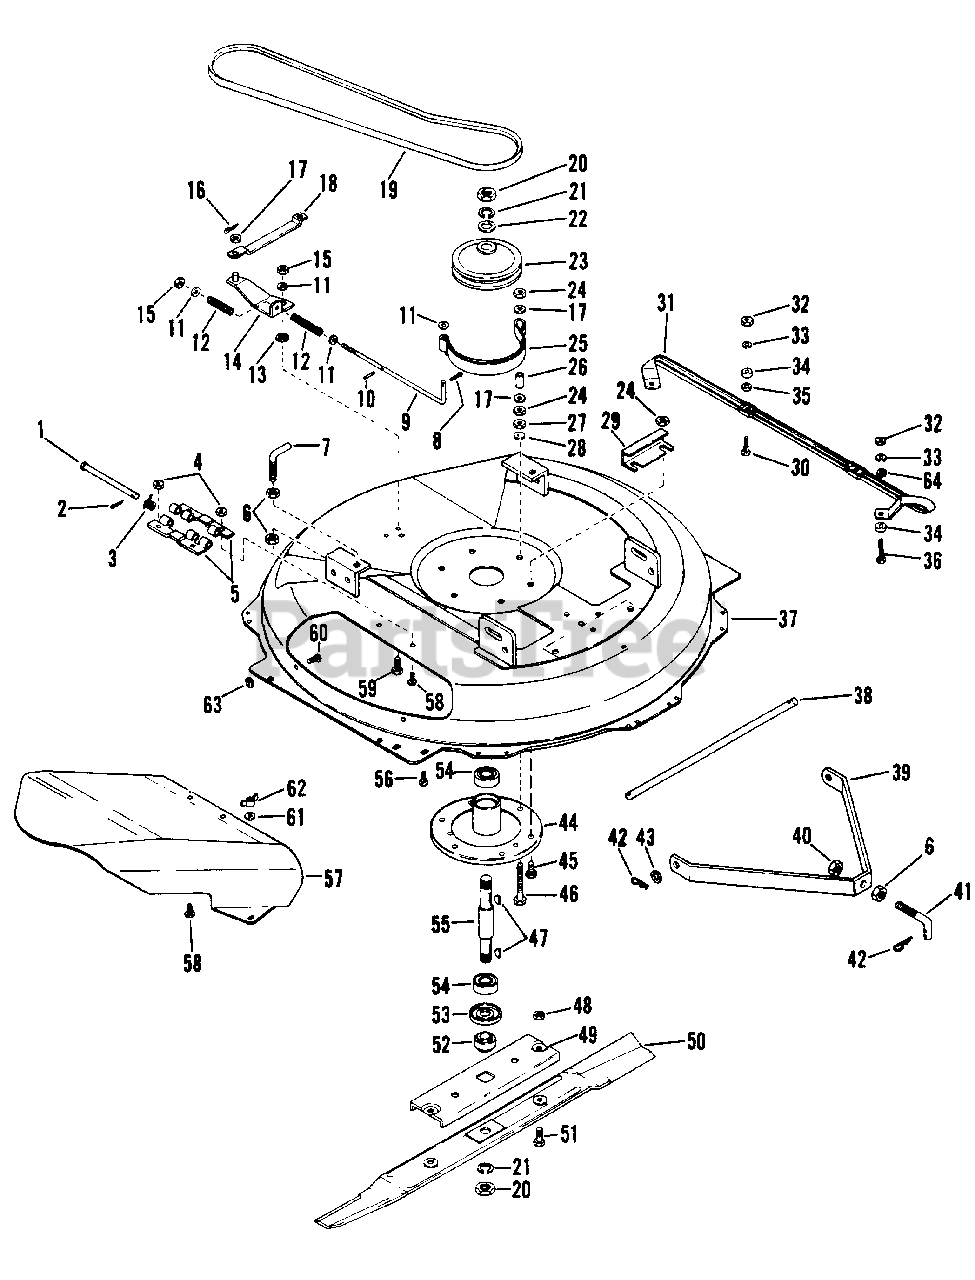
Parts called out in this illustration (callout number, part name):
1	PIN, HINGE
2	PIN, COTTER .09X.75
3	SPRING, TORSION .37 I.D.
4	NUT, LOCK 1/4-20
5	PLATE, HINGE
6	NUT, JAM 1/2-13 HEX
7	HOOK, HANGER
8	PIN, COTTER .09X.50
9	ROD, BRAKE
10	PIN, SPRING .125X1.000
11	WASHER, FLAT .312X.734X.065
12	SPRING
13	SPACER
14	ACTUATOR, BRAKE
15	NUT, LOCK 5/16-18
16	PIN, COTTER .125X1.00
17	WASHER, FLAT .406X.812X.065
18	STRAP
19	V-BELT
20	NUT, JAM 3/4-10 HEX
21	WASHER, LOCK 3/4 SP
22	WASHER, FLAT .938X1.750X.134
23	SHEAVE, MOWER
24	NUT, LOCK 3/8-16
25	BAND, BRAKE
26	SPACER
27	NUT, HEX 3/8-16
28	WASHER, LOCK 3/8 REG.
29	SUPPORT, BRAKE BAND
30	BOLT, 5/16-18X1.25 RD HD SQ NK
31	SKID, 32" ADJUSTABLE
32	NUT, HEX 5/16-18
33	WASHER, LOCK 3/8 SP HEAVY
34	SPACER
35	BUSHING, SPACER
36	BOLT, 5/16-18X1.75 RD HD SQ NK
37	DECK, 32" MOWER
38	PIN, TOW
39	STRAP, MOWER
40	NUT, LOCK 1/2-13
41	HOOK, TOW
42	HAIR PIN, INTERNAL
43	WASHER, FLAT .531X1.062X.095
44	HOUSING, SPINDLE
45	BOLT, HEX 3/8-16X.75
46	BOLT, HEX 3/8-16X3.00
47	KEY, WOODRUFF .187X.75 #9
48	NUT, LOCK 3/8-16
49	TRAY, BLADE
50	BLADE, 32" MOWER
51	BOLT, HEX 3/8-16X1.00
52	HUB, RETAINER
53	SLINGER, BEARING
54	BEARING, RADIAL
55	SHAFT, SPINDLE
56	BOLT, CARRIAGE 5/16-18X.75
57	CHUTE, DEFLECTOR
58	BOLT, 1/4-20X.625 RD HD SQ NK
59	BOLT, HEX 5/16-18X.75
60	BOLT, 5/16-18X.625 RD HD SQ NK
61	WASHER, FLAT .313X.875X.065
62	NUT, WING 5/16-18 TYPE B
63	NUT, PUSH 5/16
NS	DECAL, DANGER FOOT
NS	DECAL, NO STEP
NS	DECAL, CAUTION
NS	DECAL, WARNING EYE
NS	DECAL, DANGER HAND
